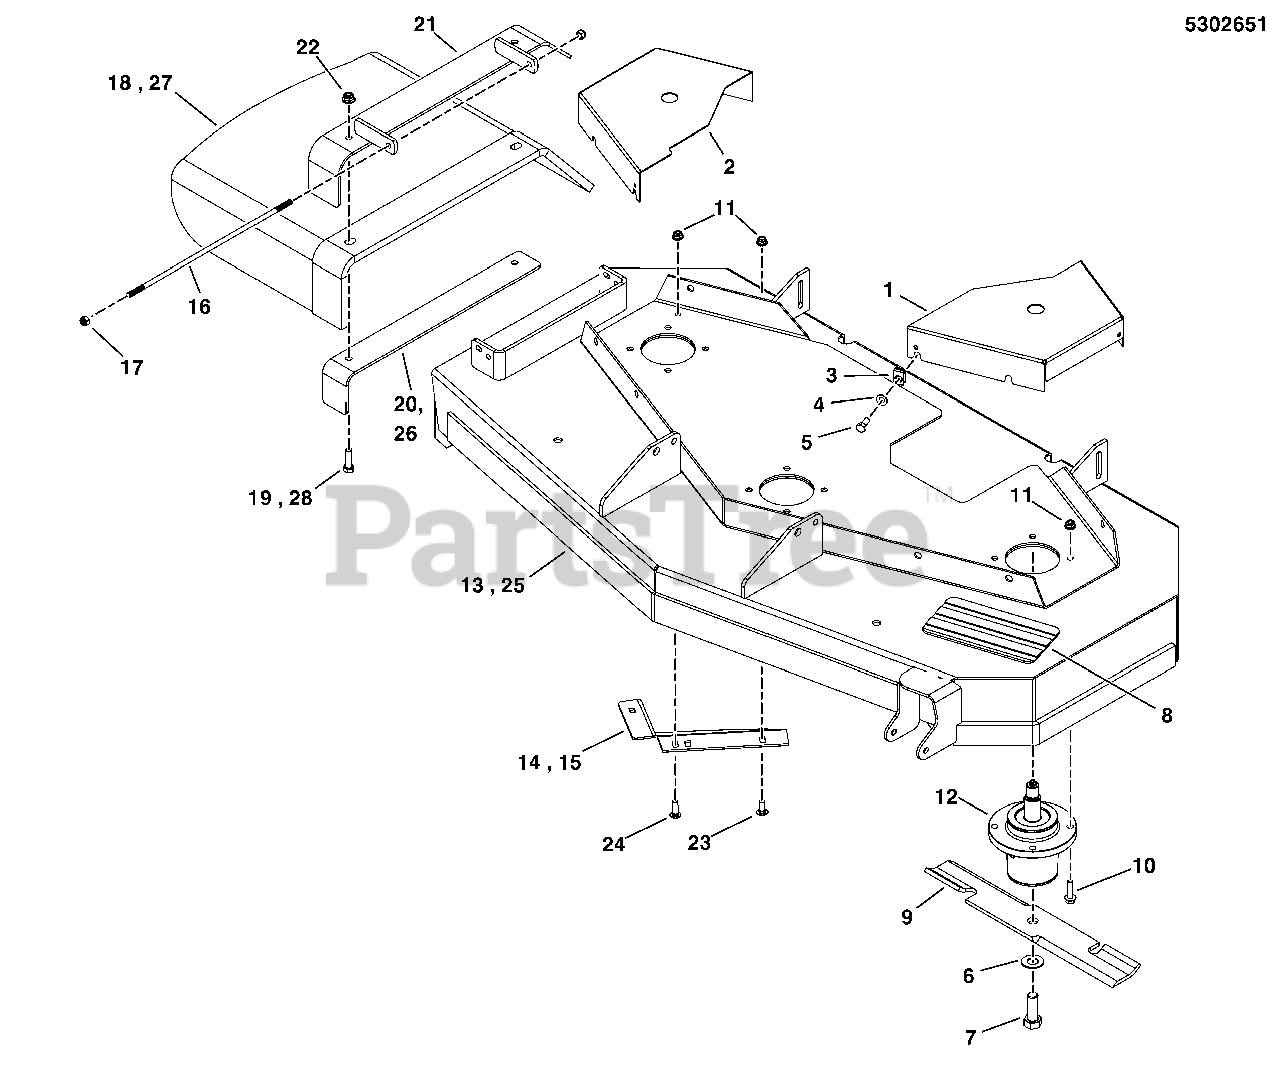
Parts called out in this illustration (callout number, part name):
1	GUARD, 48" MOWER DECK, LH
2	GUARD, 48" MOWER DECK, RH
3	BODY CLIP 5/16-18 X 1/2" DEEP
4	WASHER, 5/16" SAE
5	BOLT, 5/16-18 X 3/4 GD5
6	WASHER, 5/8 USS
7	BOLT, 5/8-11 X 1-3/4 GR8
8	SAFETY WALK, 4.00 X 7.50
9	BLADE, 16.25 X.25 X 2.5, 1 X 3.5 (SET OF 3)
10	BOLT, 5/16-18 X 1-1/4" FLANGE
11	NUT, 5/16-18 HEX NYLOCK FLANGE
12	ASSM, SPINDLE, LOW PROFILE
13	DECK SHELL W/ DECALS 48" DECK, ZT3500
14	WELD, DISCHARGE BAFFLE, 48" - BLK
15	PLATE, DEFLECTOR - BLK
16	ROD, BRAKE LINKAGE
17	NUT 5/16-24 HEX NYLON LOCK
18	CHUTE, RUBBER, BENT
19	BOLT, 3/8-16 X 1-1/2 GD5 YZ
20	SUPPORT, DISCHARGE CHUTE, 48/52 - BLK
21	WELD, FRAME CHUTE, 44/48/52 - BLK
22	NUT, 3/8-16 HEX NYLOCK FLANGE
23	BOLT, 5/16"-18 CARRIAGE, 3/4"
24	BOLT, 5/16"-18 CARRIAGE, 1"
25	DECK SHELL W/ DECALS, ZT3500 - 48
26	SUPPORT, DISCHARGE CHUTE - BLK
27	CHUTE, RUBBER DISCHARGE (5104441)
28	BOLT, 3/8-16 X 1-1/2, CARRIAGE, GD5, CZ
